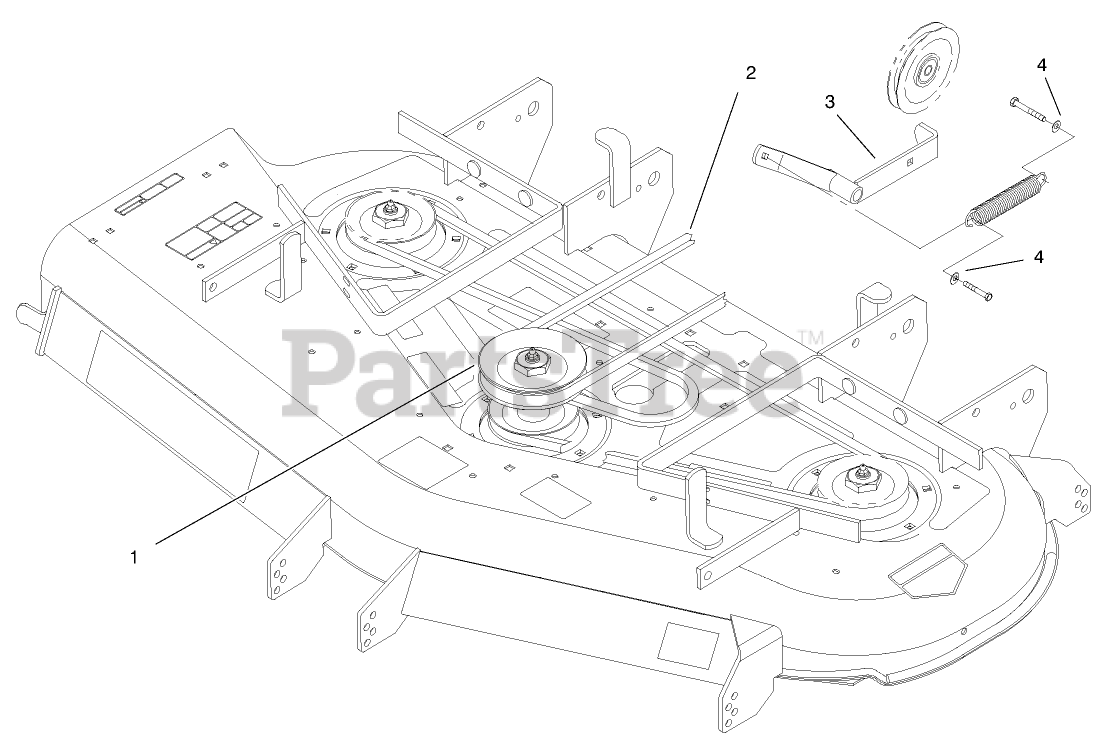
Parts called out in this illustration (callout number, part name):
1	PULLEY/HUB ASM
2	BELT (52)
3	IDLER ARM ASM
4	WASHER-FLAT
